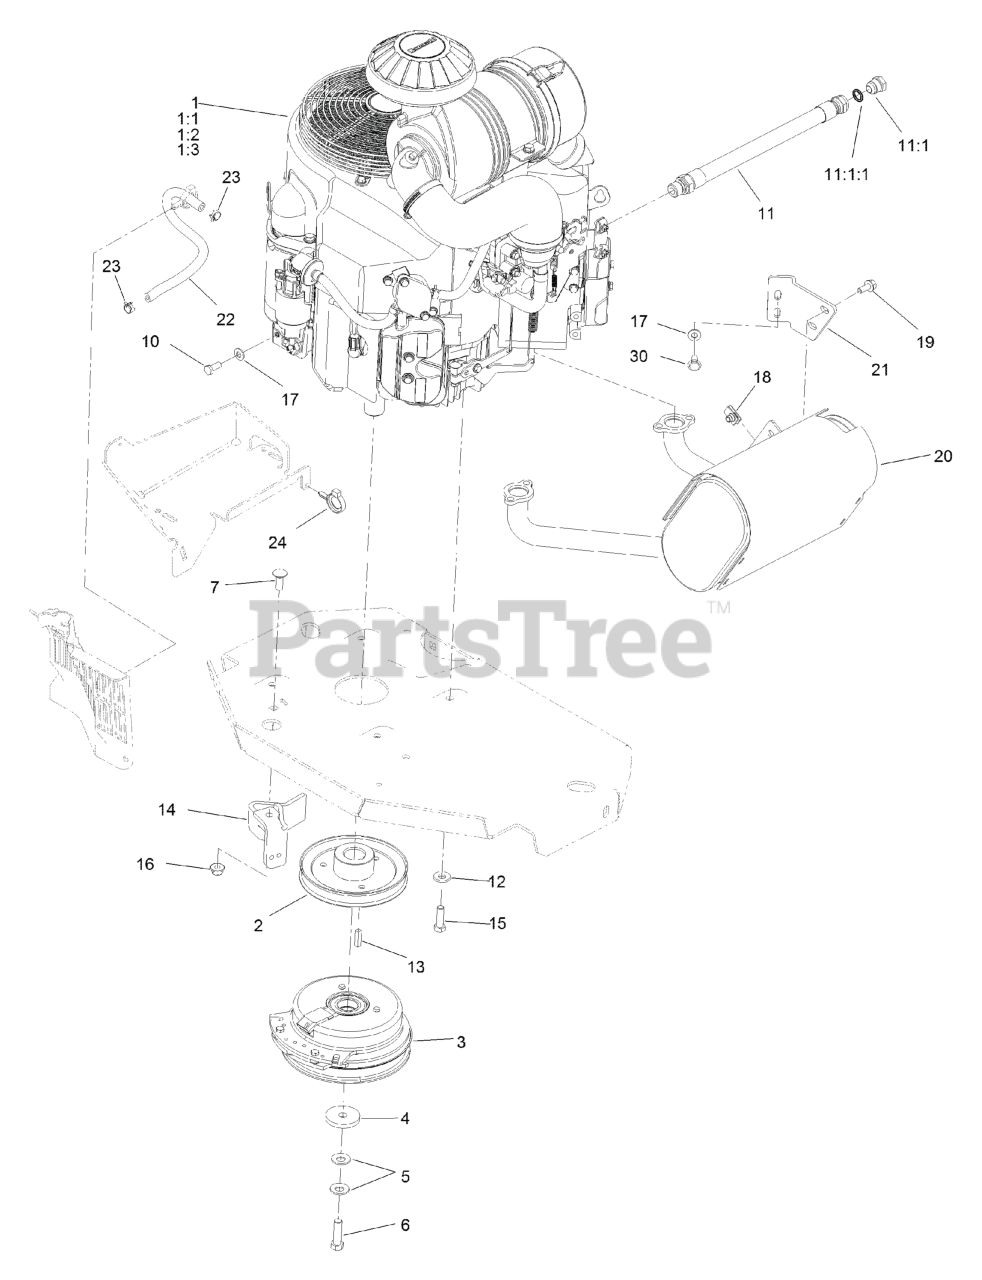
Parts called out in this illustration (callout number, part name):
1:1	Kawasaki 49065-2078 Engine Oil Filter
1:2	Kawasaki 11013-7044 Engine Air Filter
1:3	Kawasaki 11013-7045 Safety Filter
2	SHEAVE
3	CLUTCH KIT
4	WASHER-CLUTCH
5	WASHER-SPRING
6	SCREW-HH 7/16-20 X 1 1/2 W/LOCTITE
7	SCREW-CARR
10	SCREW-HH
11	ENGINE OIL DRAIN HOSE ASM
11:1	PLUG-HH
11:1:1	O-RING
12	WASHER-BELLEVILLE
14	CLUTCH-ANCHOR
15	SCREW-HH
16	NUT-HF, NI
17	WASHER-SPRING
19	SCREW-HHF
20	MUFFLER
21	BRACKET-MUFFLER
22	HOSE-FUEL
23	CLAMP-HOSE
24	CLAMP-HOSE
30	SCREW-HHF
